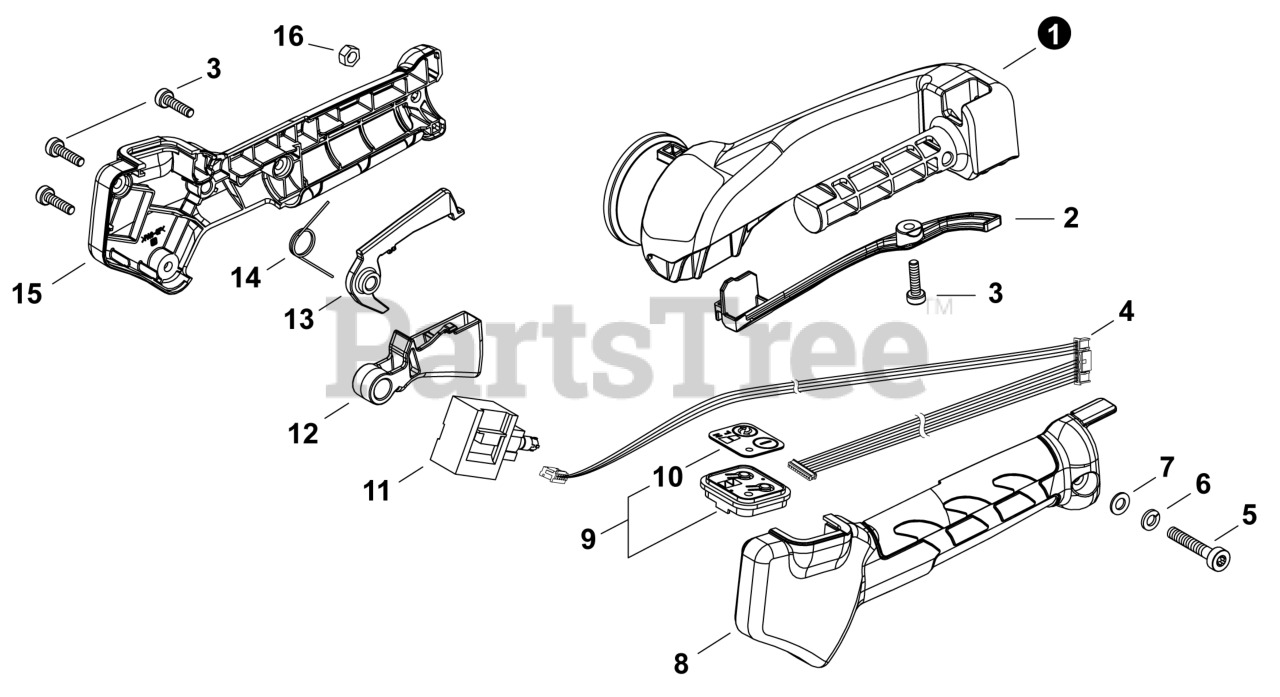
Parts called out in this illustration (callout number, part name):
1	SUPPORT, HANDLE
2	COVER, HARNESS
3	BOLT, TORX 4x16
4	HARNESS, WIRE - SWITCH
5	BOLT, TORX 5x30
6	WASHER, SPRING 5
7	WASHER 5.3x10x1
8	GRIP, HANDLE - LEFT
9	SWITCH ASSY, ON-OFF
10	LABEL - SWITCH
11	SWITCH, SPEED CONTROL
12	TRIGGER, THROTTLE
13	LOCKOUT, THROTTLE
14	SPRING, TORSION
15	GRIP, HANDLE - RIGHT
16	NUT, LOCK M5
